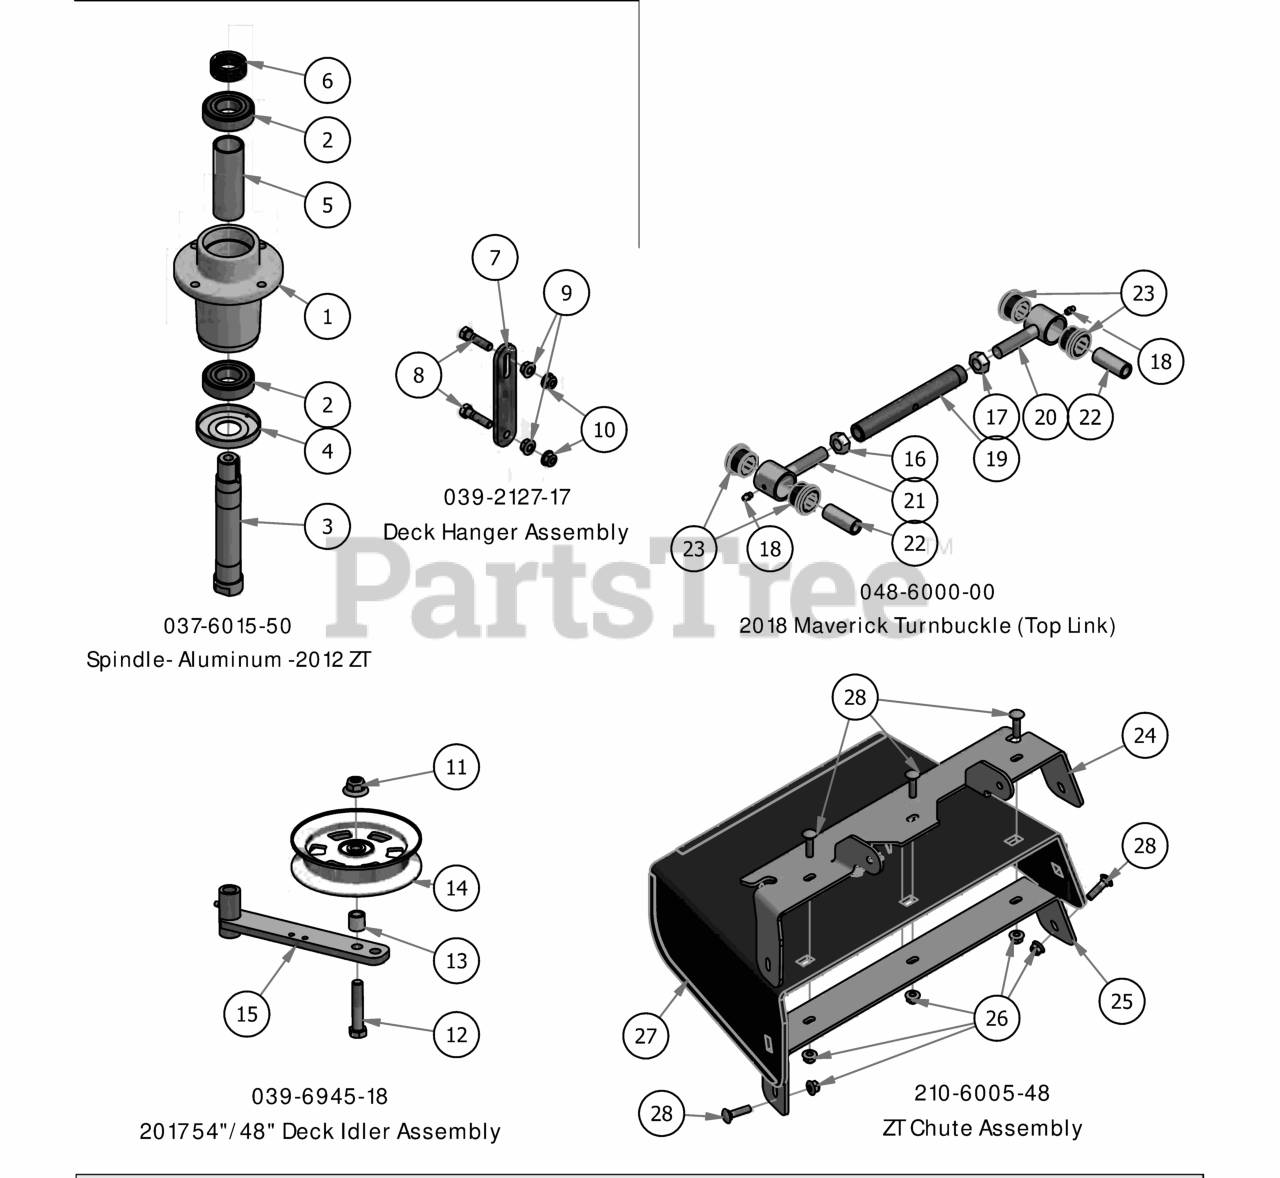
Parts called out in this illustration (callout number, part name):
1	Aluminum Spindle Housing -2010
2	Spindle Bearing, 2004 and up
3	Short Spindle Shaft w/Locking
4	Dust Cover
5	Tube Spacer for Spindle Shaft
6	Collar Spacer - Top of Spindle
7	2017 MZ/ZT Deck Hanger
8	3/8" x 1 1/2" Hex Bolt
9	3/8" Flange Nut
10	3/8" Nylock Flange Nut
11	1/2-13 Nylon Flange Nut
12	1/2" x 2 1/2" Hex Bolt
13	Spacer 3/4 OD x 1/2 ID x 3\4 Length
14	5" Idler Pully
15	Deck Idler
16	NUT, 5/8-18
17	NUT, 5/8-18LH
18	1/4-28 Grease Fitting
19	2018 Maverick Toplink Body
20	2018 Maverick Bushing Retainer Left-Handed
21	2018 Maverick Bushing Retainer Right-Handed
22	2018 Maverick Bushing Sleeve
23	2018 Maverick Bushing
24	Discharge Upper Chute Bracket
25	Discharge Lower Chute Bracket
26	5/16" Nylon Flange Nut
27	Rubber Discharge Chute
28	5/16" x 1 1/4" Carriage Bolt
